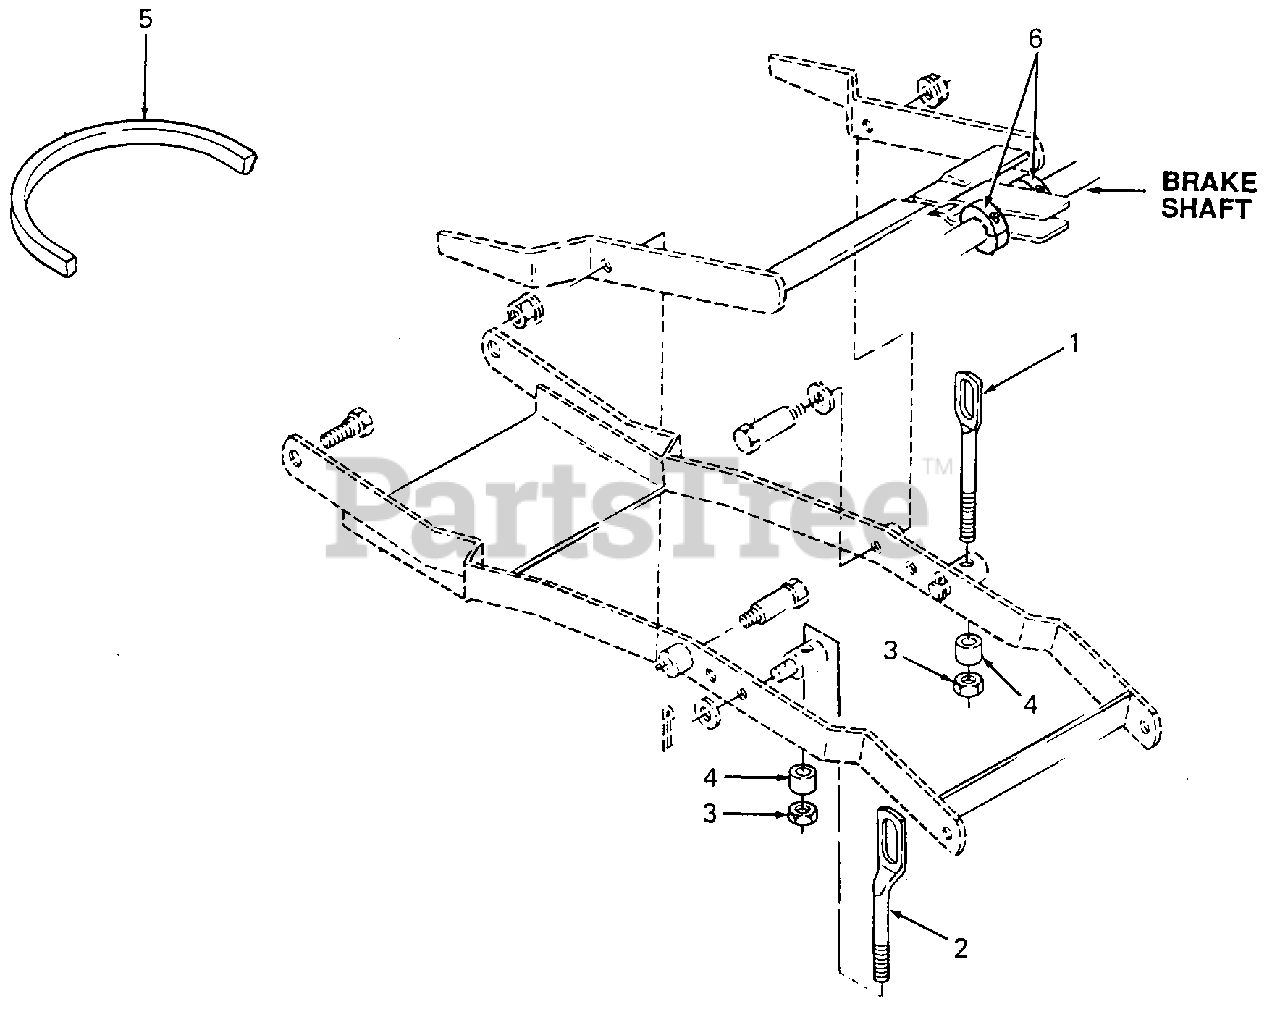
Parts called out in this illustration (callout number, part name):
1	Link, Adjustable, 7.35 Lg
2	Link, Offset Adjustable, 7.35 Lg
3	Nut, Hex Center Lock, 1/2-20
4	Spacer, .505 X .75 X .780
5	Belt, PTO, B Section X 96.5 Lg
6	Collar, Split Locking
